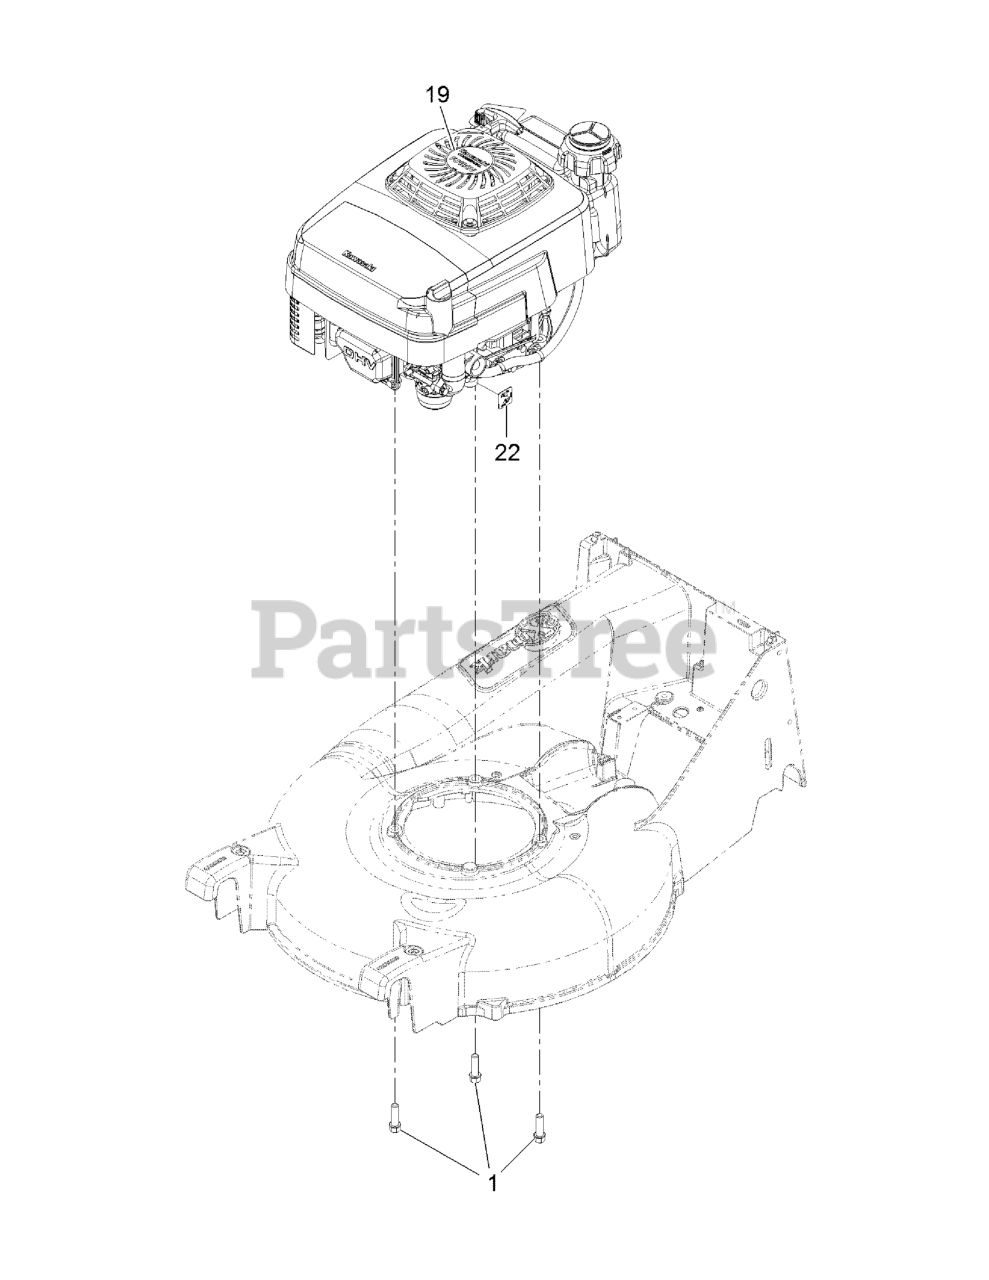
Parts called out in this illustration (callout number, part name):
1	SCREW-TAPTITE
19	DECAL-RECOIL
22	DECAL-PRIMER
